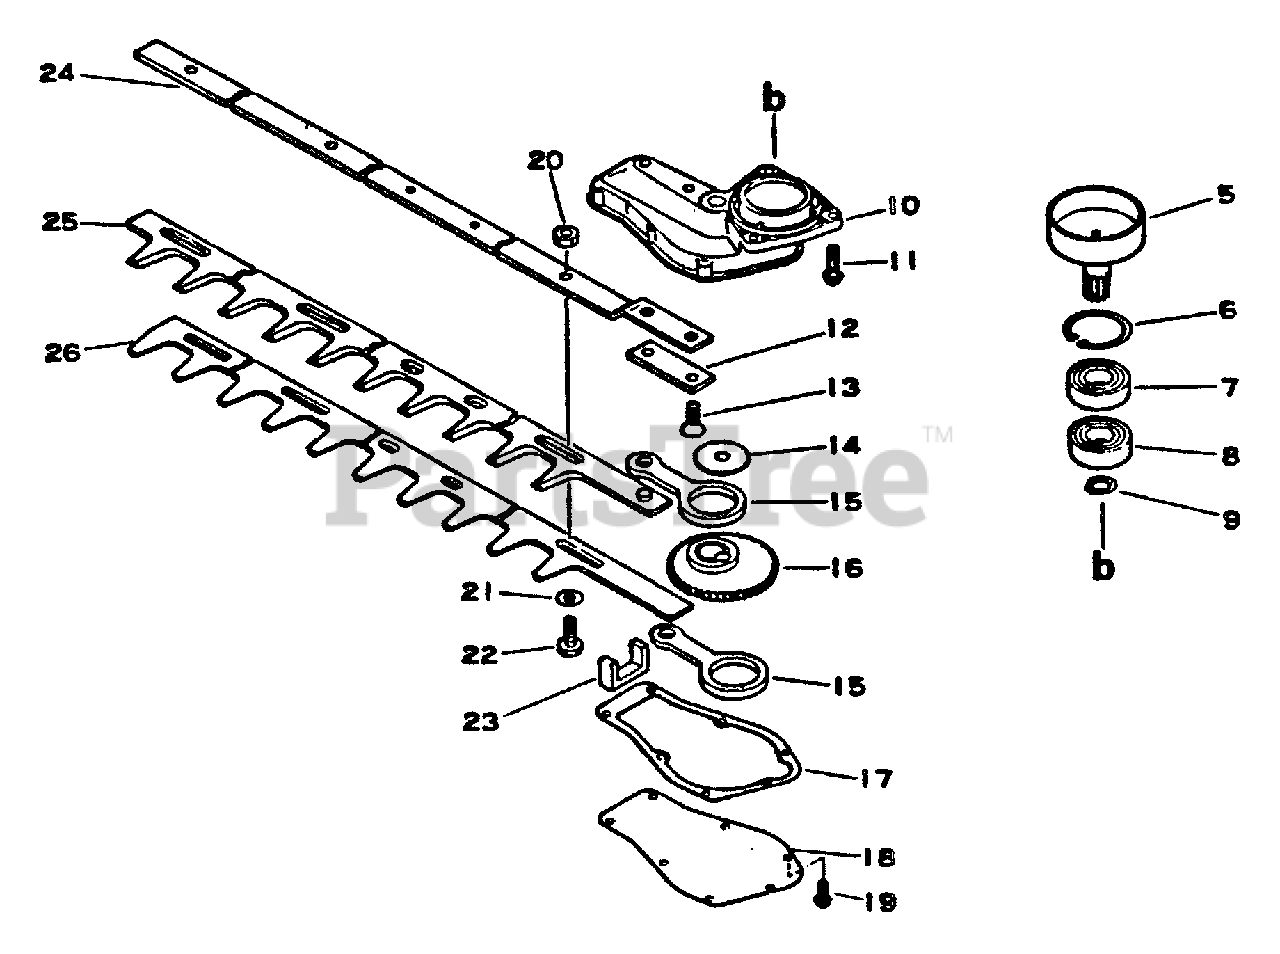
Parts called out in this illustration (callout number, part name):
5	DRUM, CLUTCH
6	RING, RETAINING - 35
7	BEARING, BALL - 6202
8	BEARING, BALL - 6202
9	RING, RETAINING - 14
10	CASE, GEAR
11	SCREW - 5X20
13	SCREW - 6X18
15	ROD, CONNECTING
16	GEAR - DRIVE
17	GASKET, GEAR CASE
18	LID, GEAR CASE
19	SCREW - 4X10
20	LOCKNUT - 6
21	WASHER - 6
23	SEAL, FELT
24	SUPPORT, BLADE
24	TRIMMER BLADE SET
25	BLADE - UPPER
26	BLADE - LOWER
29	SPANNER - 8X10mm
30	T-WRENCH - 13X19mm
